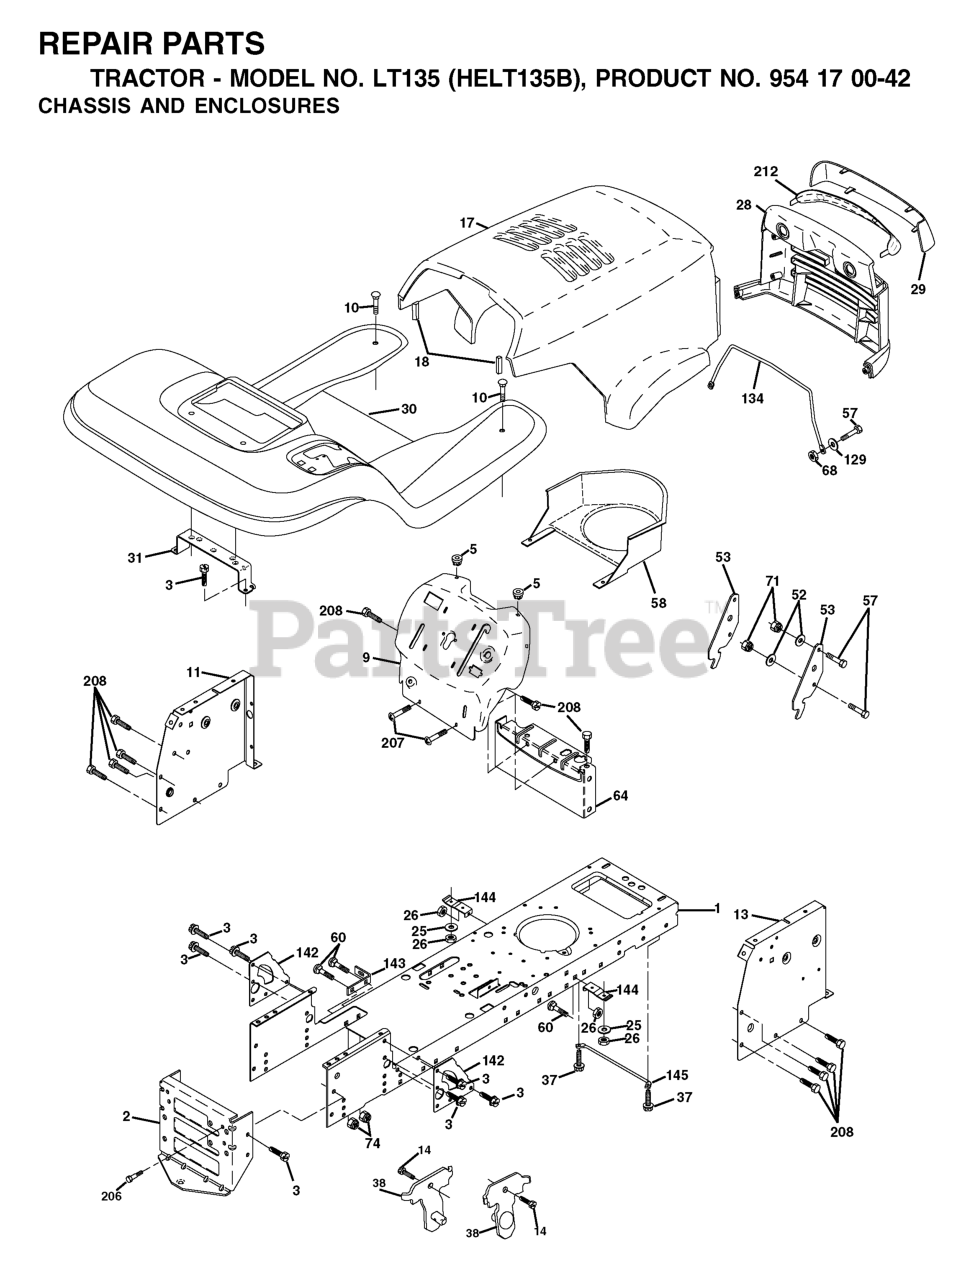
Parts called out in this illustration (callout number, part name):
1	CHASSIS STAMPING
2	DRAWBAR, 12GA
3	SCREW 3/8-16X3/4
5	BUMPER.RUBBER.HOOD
9	DASH
10	BOLT D
11	PANEL DASH LH
13	PANEL DASH RH
14	SCREW LT
17	HOOD
18	BUMPER HOOD T
25	WASHER
26	NUT
28	GRILL
29	LENS
30	FENDER FOOTREST
31	BRACKET.SUPPORT.FENDER
37	Screw 5/16-18 x 1/2 Hex, Self Tapping 5/16-18 x 1/2
38	BRACKET.ASM.PIVOT.MOWER.REAR
52	WASHER
53	BRACKET PNT PICK OFF LT/PL
57	BOLT
58	AIR DUCT P/L/LT
60	Bolt - Rd. Hd. Sq. Neckiage 3/8 16 x 3/4
64	DASH LOWER
68	NUT
71	NUT.CROWNLOCK.1/4
129	WASHER
134	ROD SUPPORT HOOD LT/PL HUS.
142	PLATE REINFORCEMENT
143	BRACKET, SWAY BAR
144	BRKT, FOOT REST
145	ROD PIVOT CHASSIS/HOOD
206	SHOULDER BOLT 5/16-18TT
207	SCREW, 5/16-18 X 1/2
208	SCREW 3/8-16X1/2
212	INSERT LENS REFLECTOR
